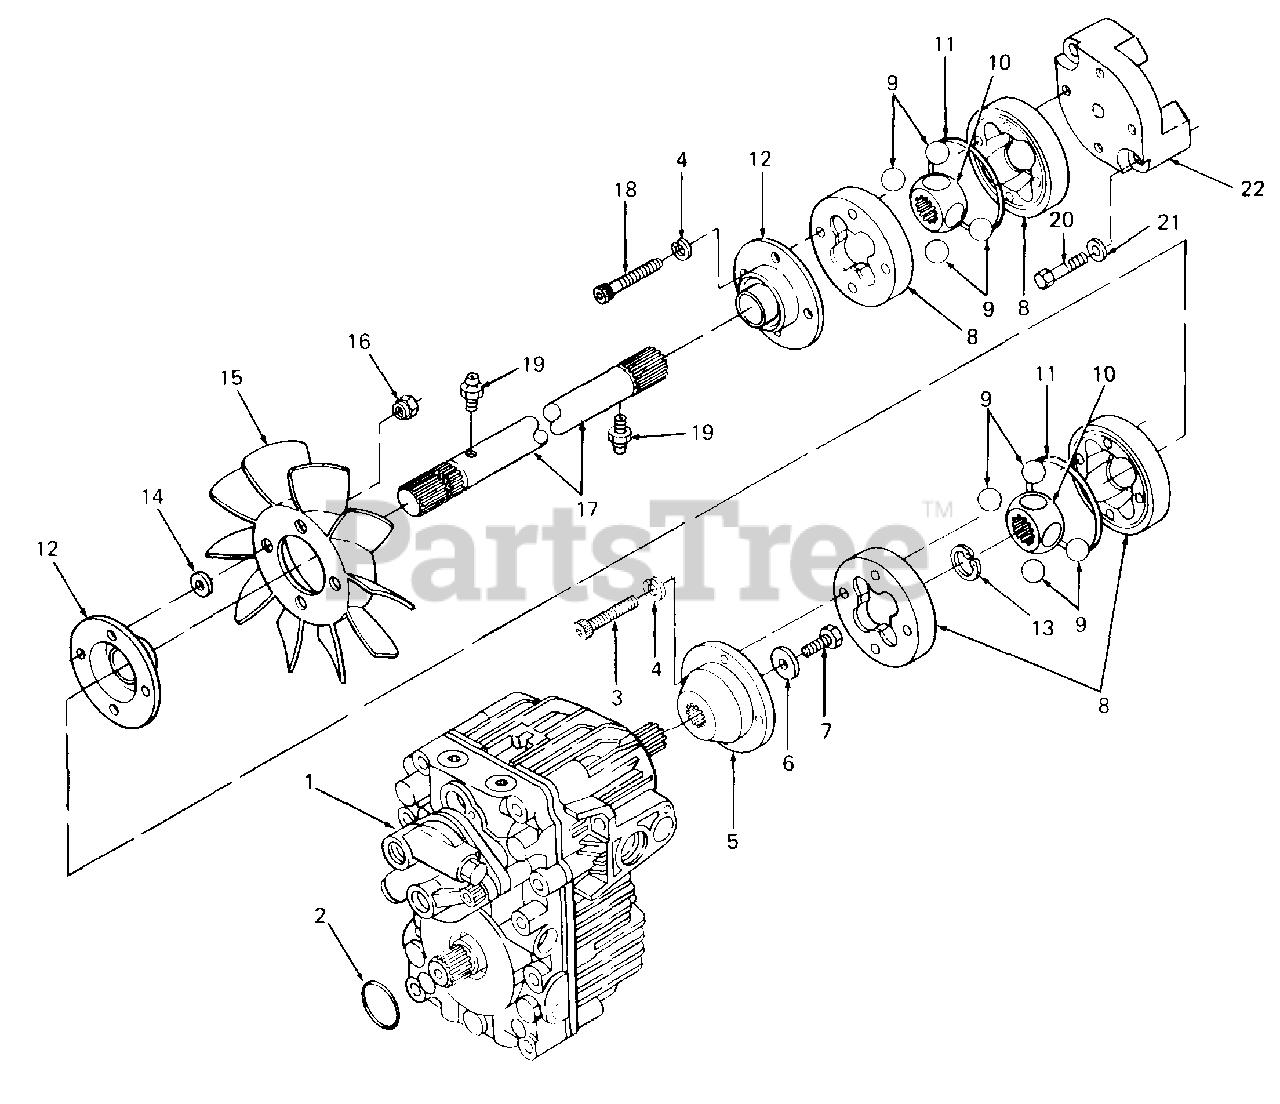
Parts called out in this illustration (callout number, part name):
1	Pump, Hydrostatic
2	O-Ring, 2.75 ID X .103 Dia
3	Screw, Socket Hd Cap, 1/4-20 X 2.0 Lg
4	Washer, Lock, 1/4
5	Adapter, Pump
6	Washer, Bell, .265 X.75 X.062 Thk
7	Bolt, Hex Patch, M6-1.0 X 20 MM Lg GR10.9
8	Coupling, Drive w/O-Ring Groove
9	Ball, Steel, 5/8 Dia Chrome
10	Hub, Drive
11	O-Ring, 2.489 X.070
12	Boot, Coupling
13	Ring, Snap
14	Washer, Flat, .25 X .62 X .052 Thk
15	Fan, 10 Blade Hydro
16	Nut, Fan, 1/4-20
17	Shaft, Drive, 20.38 Lg
18	Screw, Socket Hd Cap, 1/4-20 X 1.75 Lg
19	Fitting, Grease
20	Bolt, Hex Patch, M8-1.25 X 50 MM
21	Washer, Flat, .312 X .750 X .119 Thk
22	Adapter, Drive Shaft
